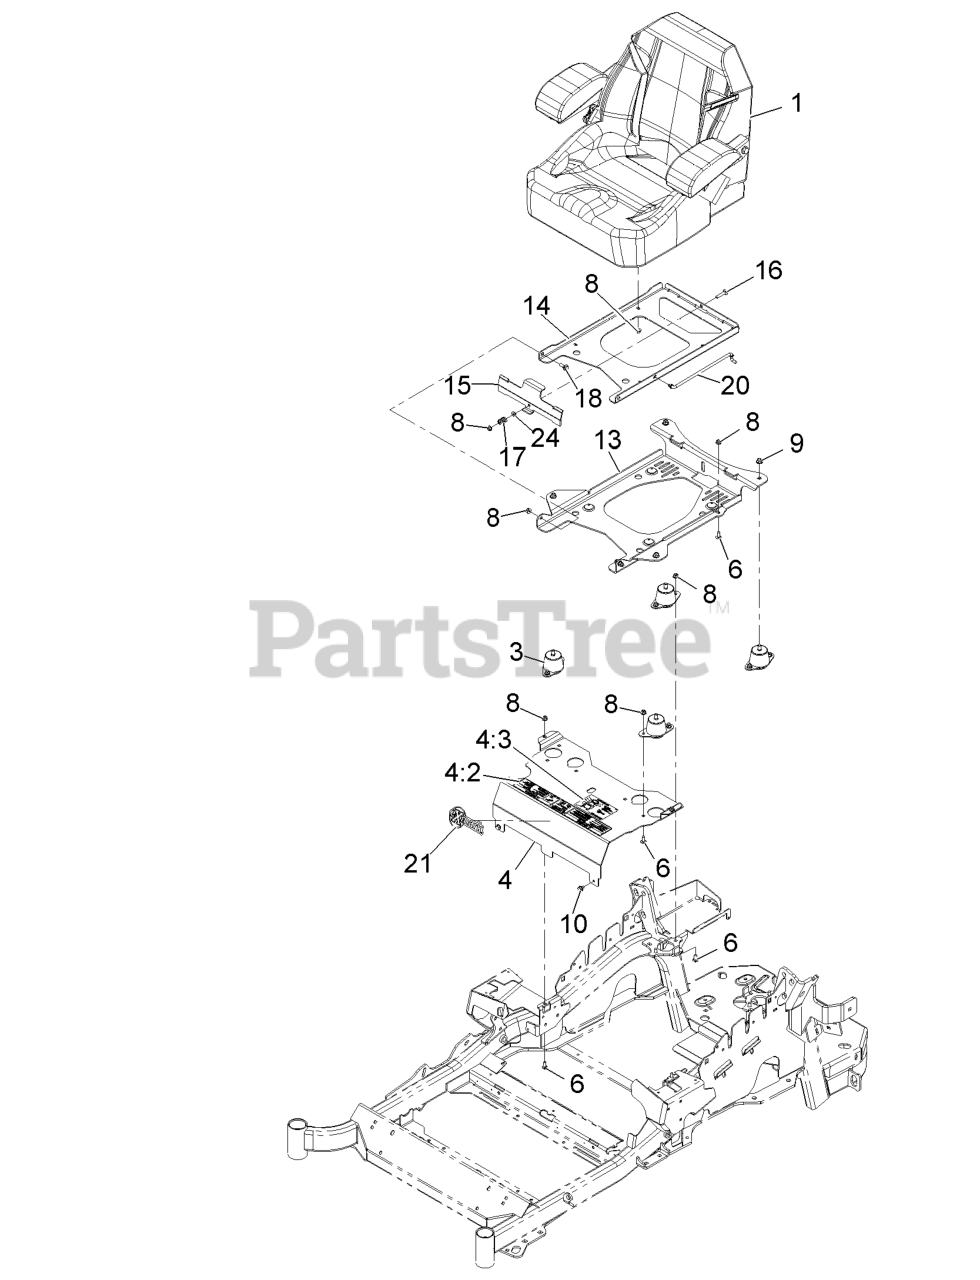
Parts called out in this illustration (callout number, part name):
3	ISOLATOR-SEAT
4	MOUNT-SEAT
4:2	DECAL-CONSOLE
4:3	DECAL-SERVICE AID
6	SCREW-CARR
8	NUT-HF, NI
9	NUT-HF, NI
13	PLATE-SUPPORT, SEAT TILT
14	PLATE-FRAME, SEAT TILT
15	PLATE-LATCH, SEAT
16	BOLT-CARR
17	SPRING-COMPRESSION
18	SCREW-SHOULDER
20	ROD-PROP
24	WASHER-PLAIN
